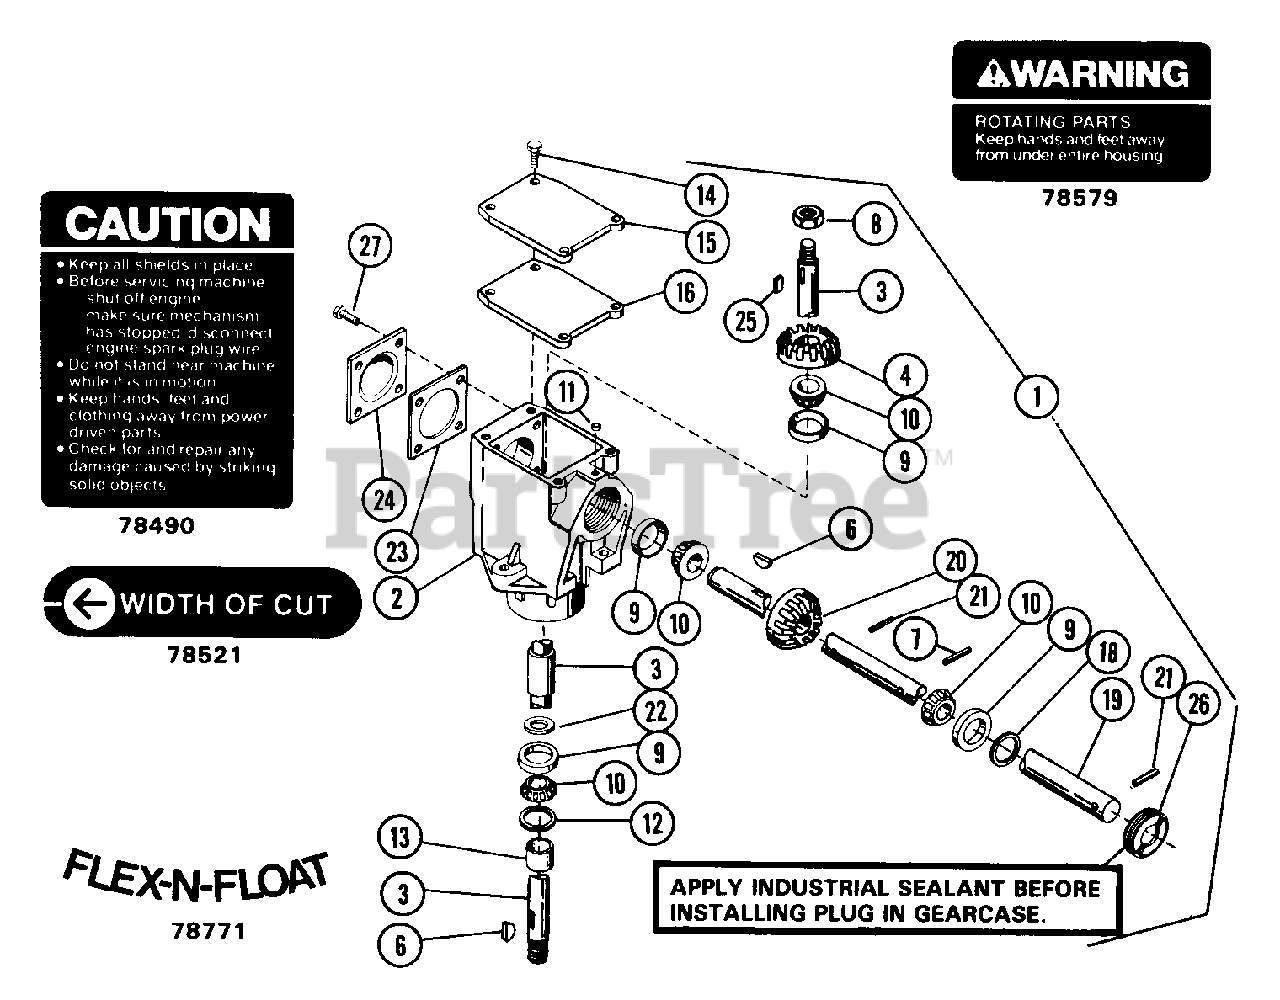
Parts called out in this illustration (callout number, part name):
1	MOWER GEAR CASE 48 IN
2	GEAR CASE
3	OUTPUT SHAFT
4	GEAR - BEVEL
6	KEY-WDRF .25X.750X.313 SAE91
7	@PIN-GRV .188X1.25 TP E ALLOY
8	NUT-JAM-CTR .562-18 PLAIN
9	BRG-CUP 1.781X.475
10	BRG-CONE .750X.61
12	SEAL 1.000X1.980X.375
13	SPACER .752X1.000X.850
14	SCR-TAP 8-32X.38 SL HWH PL 23
15	COVER, GEAR CASE
16	TOP GASKET
17	SCR-SET .25-20X.25 SKHCUPNY OH
18	SEAL .750X1.499X.225
19	SHAFT, INPUT
20	GEAR - BEVEL
21	PIN-ROLL .188X1.00
22	WSHR-FL-STL .754X1.000X.032
22	WSHR-FL-STL .811X1.25X.005
22	WSHR-FL-STL .811X1.25X.015
22	WSHR-FL-STL .811X1.25X.025
23	GASKET - SHIM KIT
24	BEARING SIDE COVER
25	KEY-SQ .25X.625X.25 SAE 8630
26	ADJUSTMENT PLUG
27	BLT-SERHFWH .31-18X.62 PL
